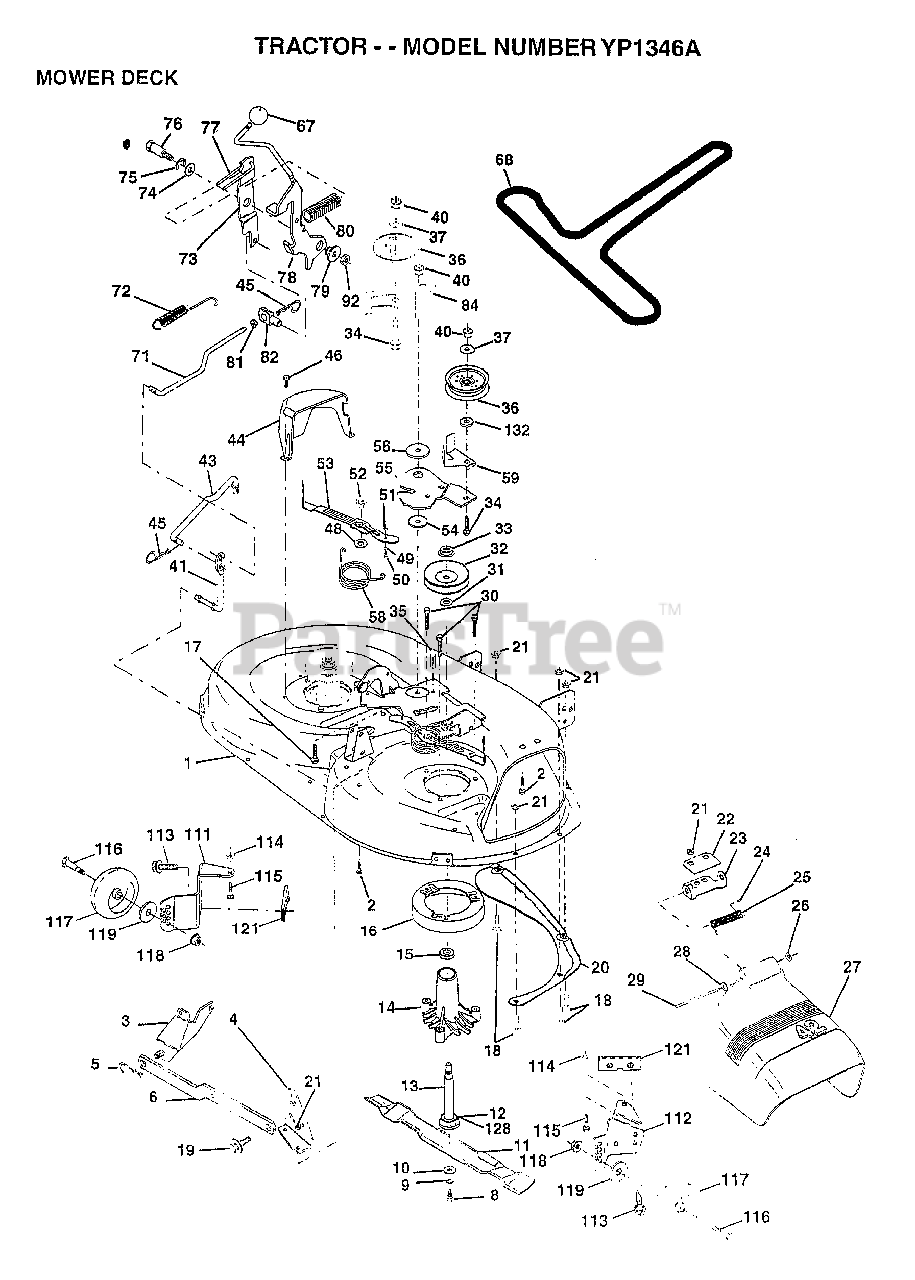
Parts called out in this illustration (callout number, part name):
1	DECK.WELD.42.
2	BOLT
3	BRKT ASM SWAY BAR
4	BRKT DECK SW BAR
8	BLADE BOLT
10	WASHER.HARD.BLADE
11	"BLADE.42"" HIPERF"
12	BEARING.BALL
14	HSG ASM MANDREL
15	BEARING
16	STRIPPER RND MWR
17	BOLT RDHD 3/8-16
18	BOLT
19	BOLT SHD 5/16-18
22	STIFFENER BRKT
23	DEFLECTOR BRKT
24	CAP-SLEEVE LT
25	SPRING TORSION
26	NUT PUSH M
27	DEFLECTOR.SHIELD
28	WASHER
29	HINGE ROD
31	WASHER
32	PULLEY.MANDREL.42
34	BOLT
35	XMAS TREE FASTNER
36	FLAT IDLER PULLEY
37	WASHER
41	PIVOT ROD
43	ROD CLUTCH W/NIBS
44	GUARD MAND LH BLK
45	RETAINER M
46	SCREW.1/4-20X5/8
48	HARD SMALL WASHER
49	ROLLER ASM-CAM
50	SHOULDER BOLT
51	LOCKNUT
52	BOLT.SHLD.5/16-18
54	HARDENED WASHER
55	ARM-IDLER
56	SPACER RETAINER
58	SPRING TORSN BRAK
59	GUARD IDLER TUV
68	BELT-V.SEC.46.KEL
71	ROD CLUTCH 38/42
72	RETURN SPRING
73	CLUTCH ARM SECOND
74	WASHER
75	RING
76	SHOULDER BOLT
77	SPRING KEEPER
78	LEVER ASM-CLUTCH
79	BUSHING
80	SPRING.CLUTCH.MWR
81	TRUNION ADJ
82	NUT
84	BRACKET ASM IDLER
92	NUT
111	BRACKET.GWHL.LH.
112	BRACKET.GWHL.RH.
113	SCREW
116	BOLT.SHOULDER
117	WHEEL GAGE DONUT
118	LOCKNUT
119	WASHER
121	BRACKET.EXTRD.GWL
128	WASHER.FELT.
132	WASHER GT
